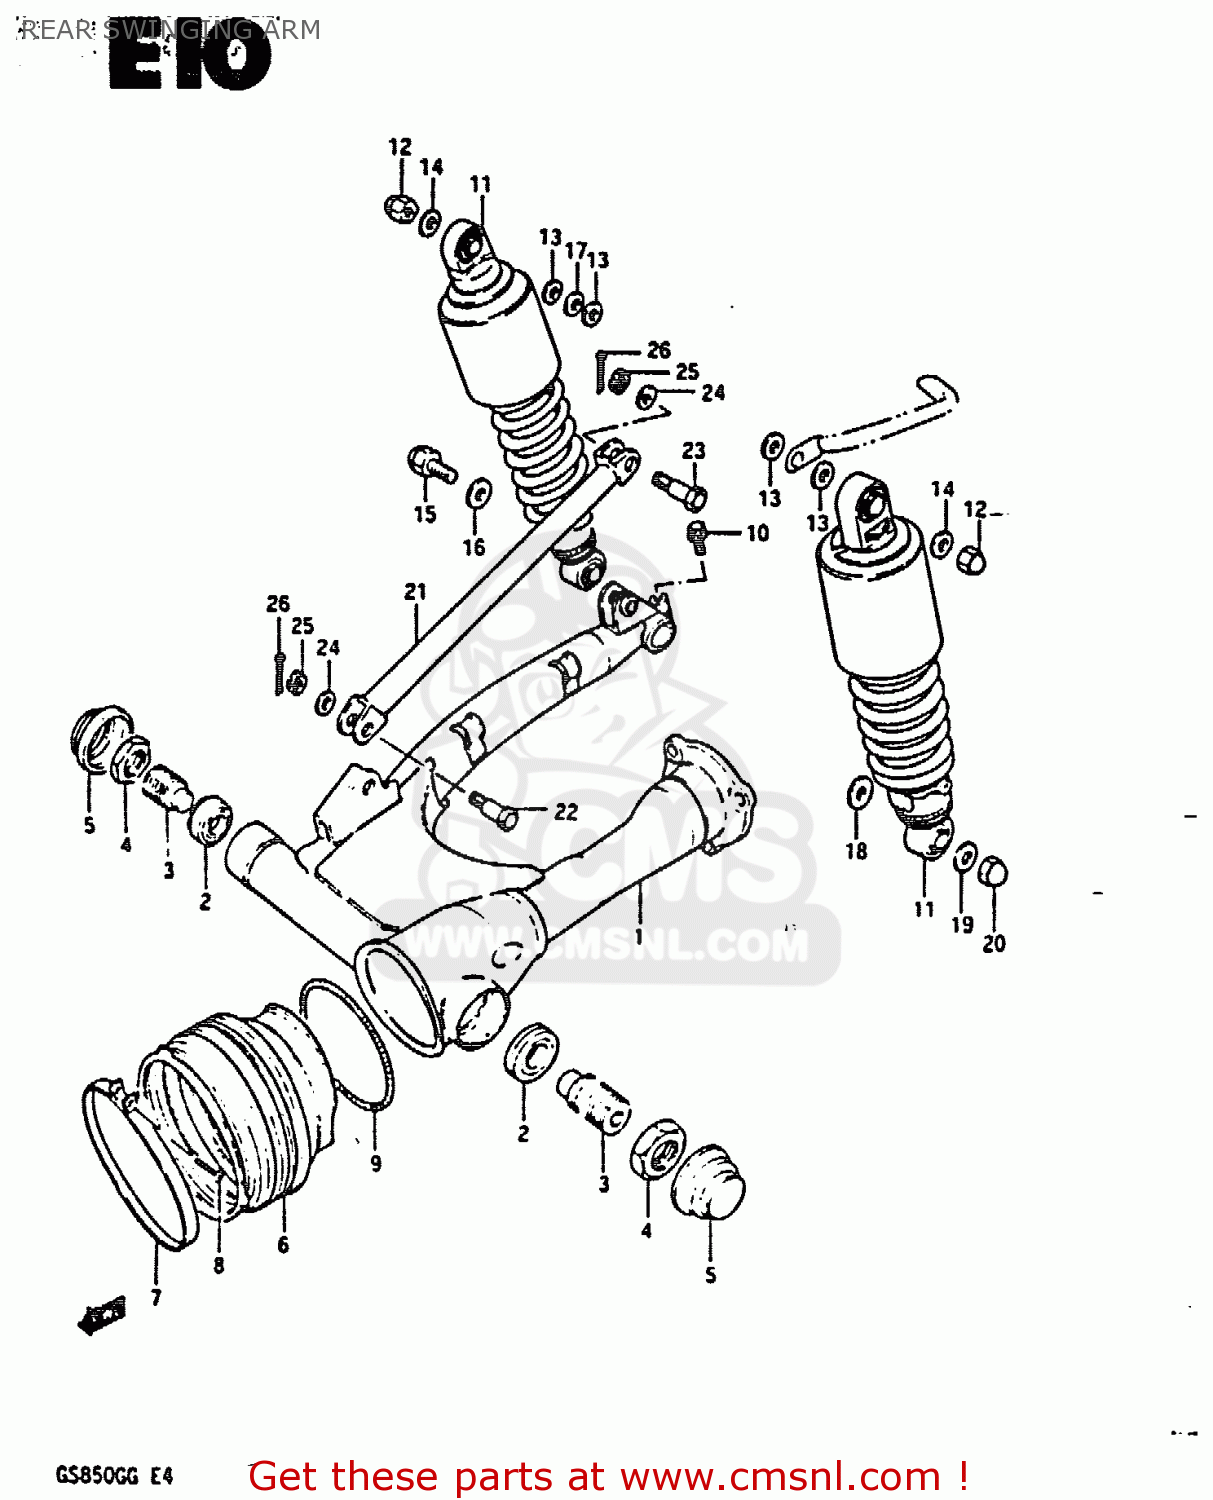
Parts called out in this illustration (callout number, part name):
1	SWING ARM SET,REAR (B
2	BEARING(17X40X13.25)
3	BOLT,REAR SWING ARM PIVOT
4	NUT
5	CAP,REAR SWING ARM PIVOT
6	BOOT,PROPELLER SHAFT
7	CLAMP
8	SCREW 4X25
9	SPRING,PROPELLER SHAFT
10	BOLT
11	ABSORBER ASSY,RR SHOCK
12	NUT
13	WASHER
14	WASHER
15	BOLT 12X33
16	WASHER (12.5X24X1.6)
17	WASHER (12.5X24X3.2)
18	WASHER
19	WASHER
20	NUT, LOWER LH
21	TORQUE LINK,REAR
22	BOLT
23	BOLT(10X39)
24	WASHER 10MM
25	NUT
26	PIN 20X20
